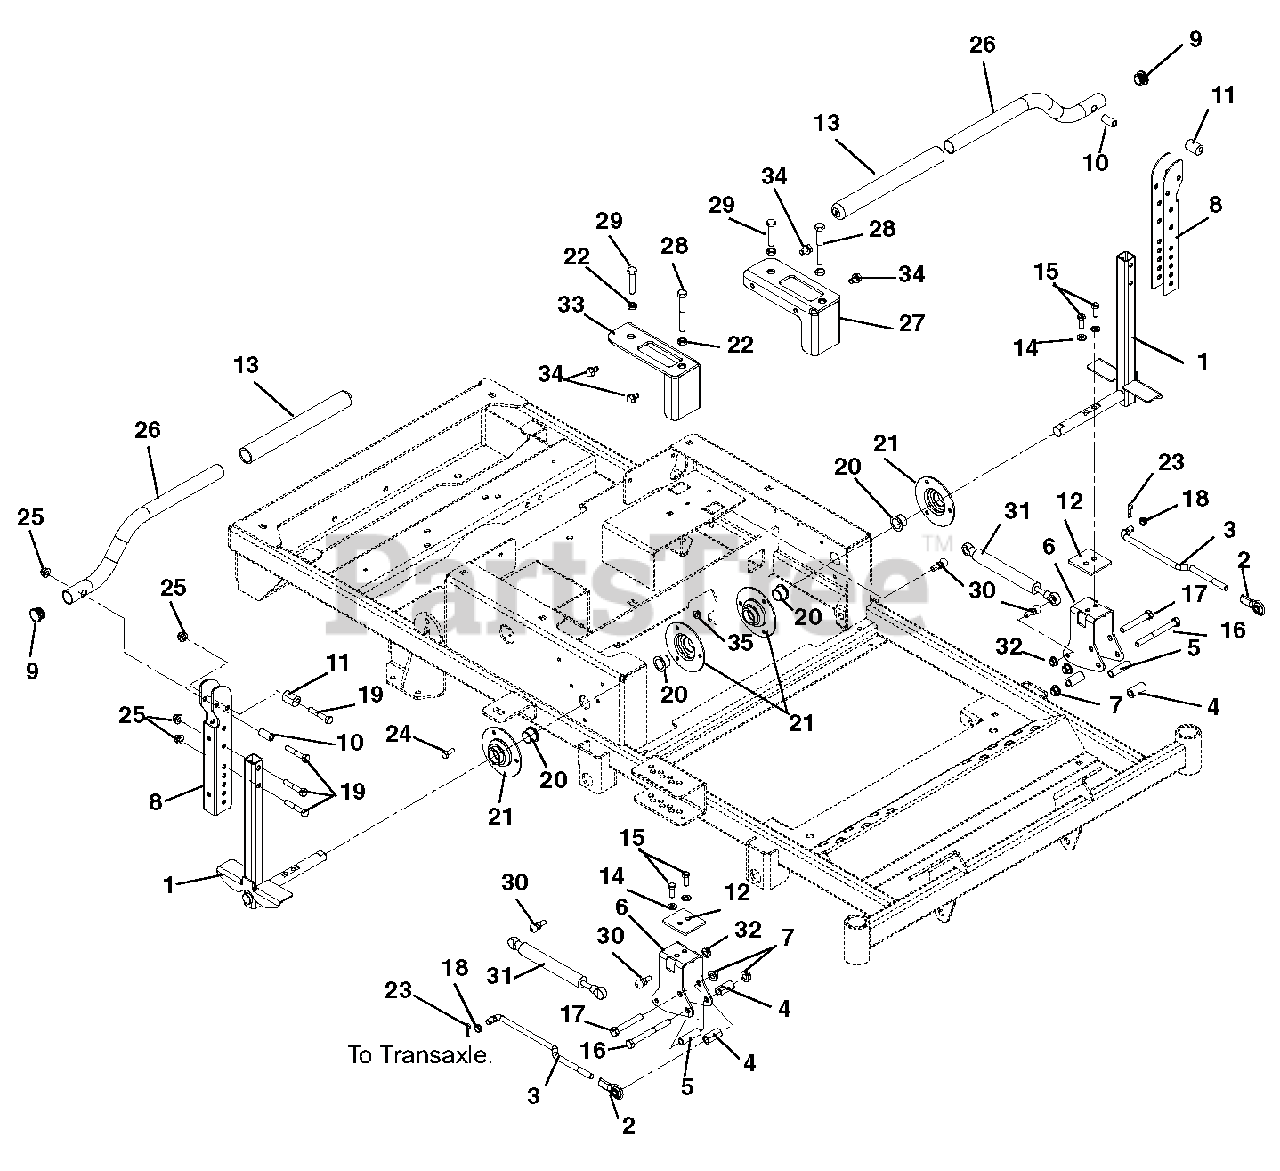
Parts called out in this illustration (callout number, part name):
1	WMT, CONTROL ARM
2	ROD END, .38 RH
3	LINK, TRANSMISSION
4	BSHG, SPCR .390X.625X1.25 PM
5	SPACER, STEERING
6	BRKT, STEERING
7	@NUT-LK-NYL-FLG .38-16 YWZC
8	CHANNEL, UPPER HANDLEBAR
9	CAPLUG, HANDLEBAR
10	BSHG, SPCR .330X.500X1.01 PM
11	BSHG,ECCEN .328X.750X1.01 PM
12	PLATE, STEERING REINFORCING
13	HANDLE GRIP
14	@WSHR-LK .31X.078 REG YWZC
15	BLT-HEX .31-18X1.00 GR8 YWZC
16	@BLT-HEX .38-16X3.75 GR5 YWZC
17	@BLT-HEX .38-16X2.50 GR5 YWZC
18	BUSHING, POLYLINER-.38 SNAPIN
19	@BLT-HEX .31-18X1.75 GR5 YWZC
20	BSHG-FLG .750X1.000X.625X1.250
21	BEARING FLANGE
22	NUT-HEX-JAM .375-16 YWZC
23	PIN-HAIR INT .08X.18X1.18 YWZC
24	@BLT-HEX .25-20X.75 GR5 YWZC
25	@NUT-LK-NYL-FLG .31-18 YWZC
26	HANDLEBAR, ZTXL
27	BRACKET, LH SPEED CONTROL
28	BLT-HEX .38-16X3.00 GR5 FTH YZ
29	BLT-HEX .375-16X1.750 FTD YWZC
30	STUD- BALL
31	DAMPER, ZT XL
32	@NUT-LK-TOP-FLG .31-18 YWZC
33	BRACKET, RH SPEED CONTROL
34	@SCR-TAP .31-18X.50 HWH TR YWZ
35	@NUT-LK-TOP-FLG .25-20 YWZC
